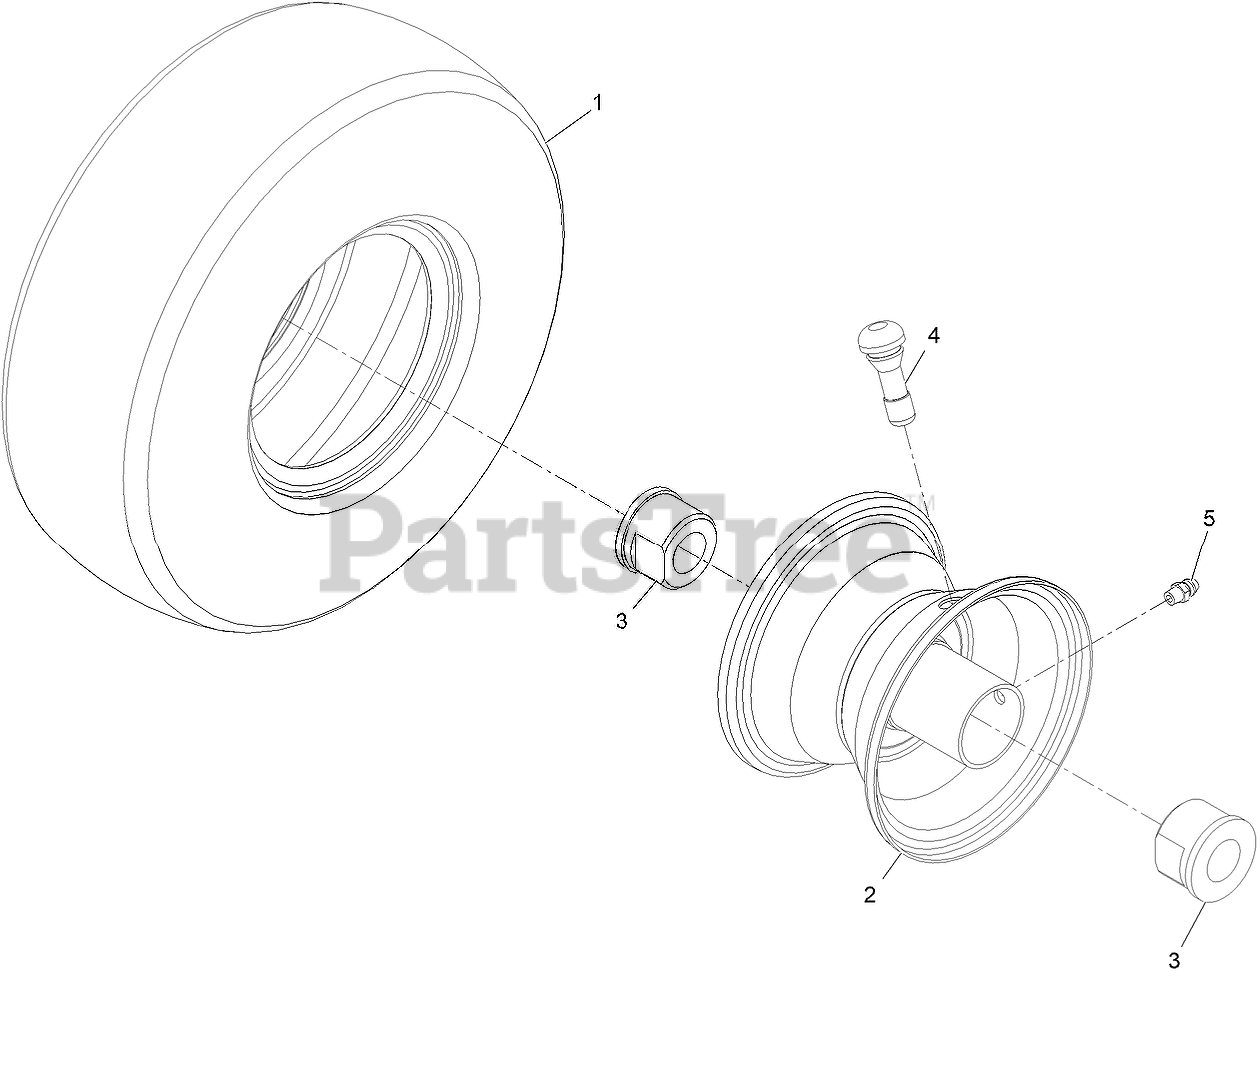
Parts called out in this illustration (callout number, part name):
1	Tire
3	BUSHING-FLANGE
4	Stem-Valve
5	FITTING-GREASE
